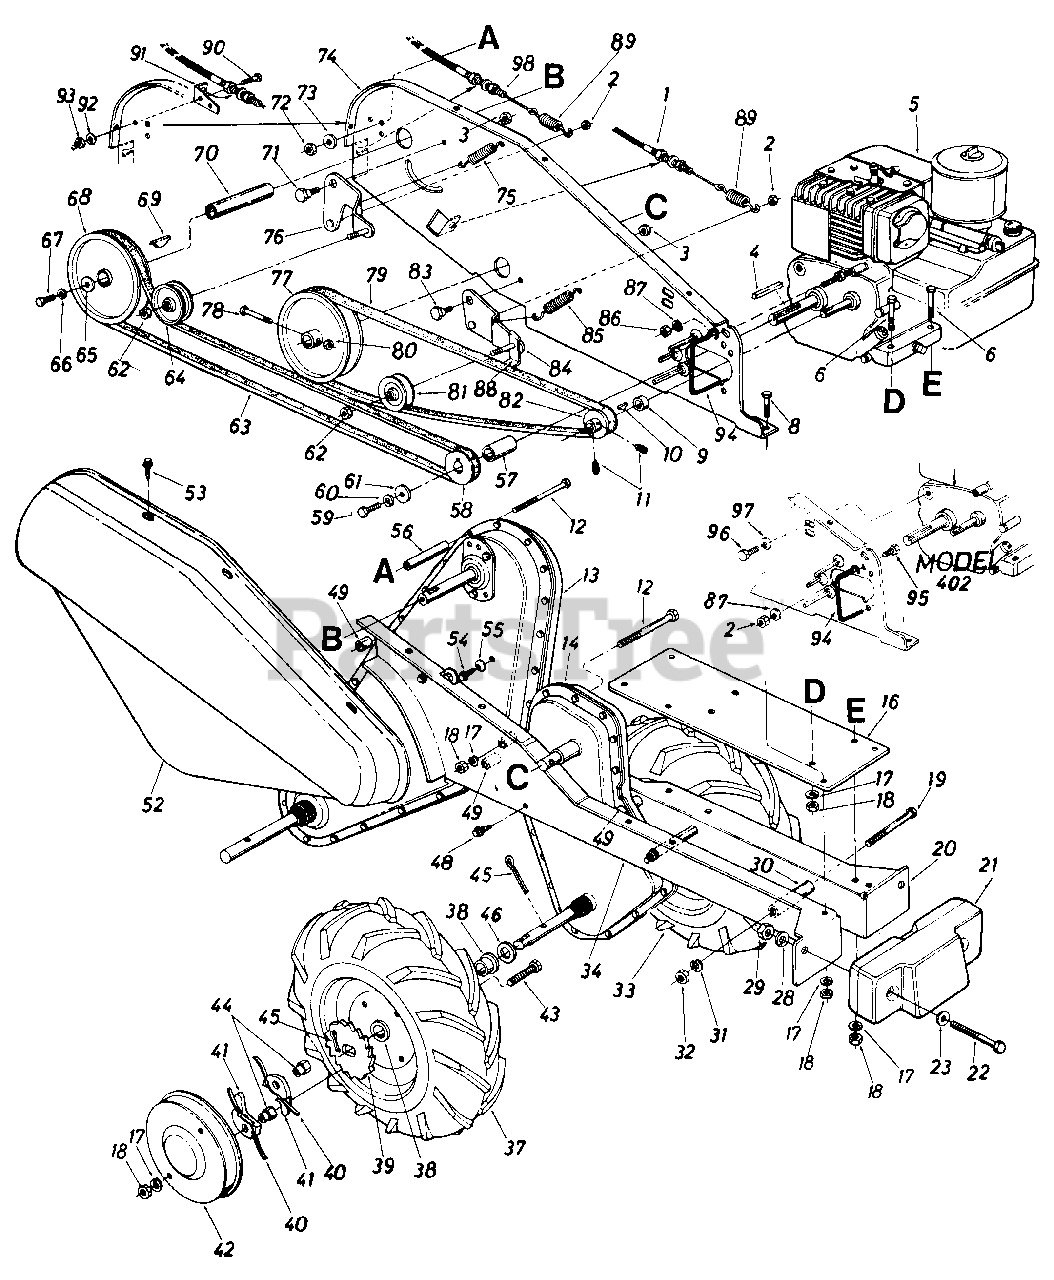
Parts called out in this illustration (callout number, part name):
1	Clutch Control Cable
2	Hex Cent. L-Nut 1/4-20 Thd.
3	Hex Cent. L-Nut 3/8-16 Thd.*
4	Sq. Key 3/16" Dia. x .75
5	Engine
6	Hex Bolt 5/16-18 x 1.50" Lg.*
8	Hex Bolt 5/16-18 x .75" Lg.*
9	Spacer .51 " I.D. x 3/4" O.D. x .39" Lg.
10	Hi-Pro Key #5 Woodruff
11	Set Scr. 1/4-28 x .25" Lg.
12	Hex Bolt 5/16-18 x 3.0" Lg.*
13	Chain Case Ass'y. Comp. Tines
14	Chain Case Ass'y. Comp. Wheels
18	Hex Nut 5/16-18 Thd.*
19	Hex Bolt 3/8-24 x 3.0" Lg.*
22	Hex Bolt l/2-13 x 4.0" Lg.*
23	Fl-Wash. 1/2" I.D. x 1.0" O.D.
28	L-Wash. 1/2" I.D.*
29	Hex Nut 1/2-1 3 Thd. *
30	Spacer 3/8" I.D. x 5/8" O.D. x 2.18" Lg.
31	L-Wash. 3/8" I.D.*
32	Hex Nut 3/8-24 Thd.*
33	Comp. Wheel Ass'y.L.H.
38	Flange Brg. 7/8" I.D. x 1.12" Lg.
39	Ratchet Wheel
40	Nylon Spring
41	Pawl.44" I.D.
42	Wheel Cover
43	Hex Bolt 5/16-18 x 1.25" Lg.*
44	Special Hex Nut 5/16-24 Thd.
45	Coter Pin 1/8 Dia. x 1.25*
46	Fl-Wash. 7/8" I.D. x 1-3/8" O.D. x .06
48	Hex Wash. Self-Tap Scr. 5/16-24 x .50" Lg.
49	Spacer 5/16" I.D. x 16 Ga. x .96" Lg.
52	Belt Cover
53	Hex Wash. S-Tap Scr. 1/4-20 x .50" Lg.
54	Hex Wash. S-Tap Scr. 1/4-20 x 3/8" Lg.
55	Bell-Wash. 1/4" I.D.
56	Spacer 3/8 I.D. x 1/2" O.D. x 2.0" Lg.
57	Spacer 3/4" I.D. x 1.12" O.D. x 1.56" Lg.
58	1/2" "V"-4L Pulley 3/4" I.D. x 2.59" O.D.
59	Hex Bolt 5/16-24 x 1.0" Lg.
60	L-Wash. 5/16" l.D.
61	Fl-Wash. 5/16" I.D. x 1.25n O.D.
62	Hex L-Nut 3/8-24 Thd.
63	"V"-Belt
64	Fl-ldler Pulley 3.75" O.D. x 3/8" I.D.
65	Fl-Wash. .25" I.D. x .93" O.D. x .120
66	L-Wash. 1/4" I.D.
67	Hex Bolt 1/4-28 x .75" Lg.
68	Split Pulley 6" Dia. x 5/8" I.D.
69	Hi-Pro Key
70	Spacer
71	Shld. Bolt 1/2" Dia. x .210" Lg.
72	Hex Nut 5/16-18 Thd.
73	L-Wash. 5/16" I.D.
74	Side Plate Ass'y.
75	Ext. Spring .50" O.D. x l.55n Lg.
76	Idler Bracket Ass'y.Tines
77	Pulley 6" Dia. x 5/8" l.D.
78	Hex Bolt 1/4-28 x 1.50" Lg.
79	"V"-Belt
80	Hex Cent. L-Nut 1/4-28 Thd.
81	"V"-Idler Pulley 2-5/8" O.D.
82	1/2" "V"-Pulley 21/4n O.D. x 50" 1 D
83	Shld. Bolt 1/2" Dia. x .160"
84	Idler Bracket Ass'y-Wheels
85	Ext. Spring .50" O.D. x 1.55 Lg.
86	Hex Nut 1/4-20 Thd.
87	Bell-Wash. 1/4" I.D.
88	Belt Keeper Ass'y.
89	Ext. Spring
90	Hex Bolt 5/16-18 x .75n
91	Clutch Cable Brkt.
92	Lock Washer 5/16" l.D.
93	Hex Nut 5/16-18 Thd.
94	Belt Keeper
95	Hex Bolt 1/4-20 x 1.25" Lg.
96	Hex Bolt 5/16-24 x .62" Lg.
97	Bell-Wash. 5/16" I.D.
98	Clutch Control Cable
